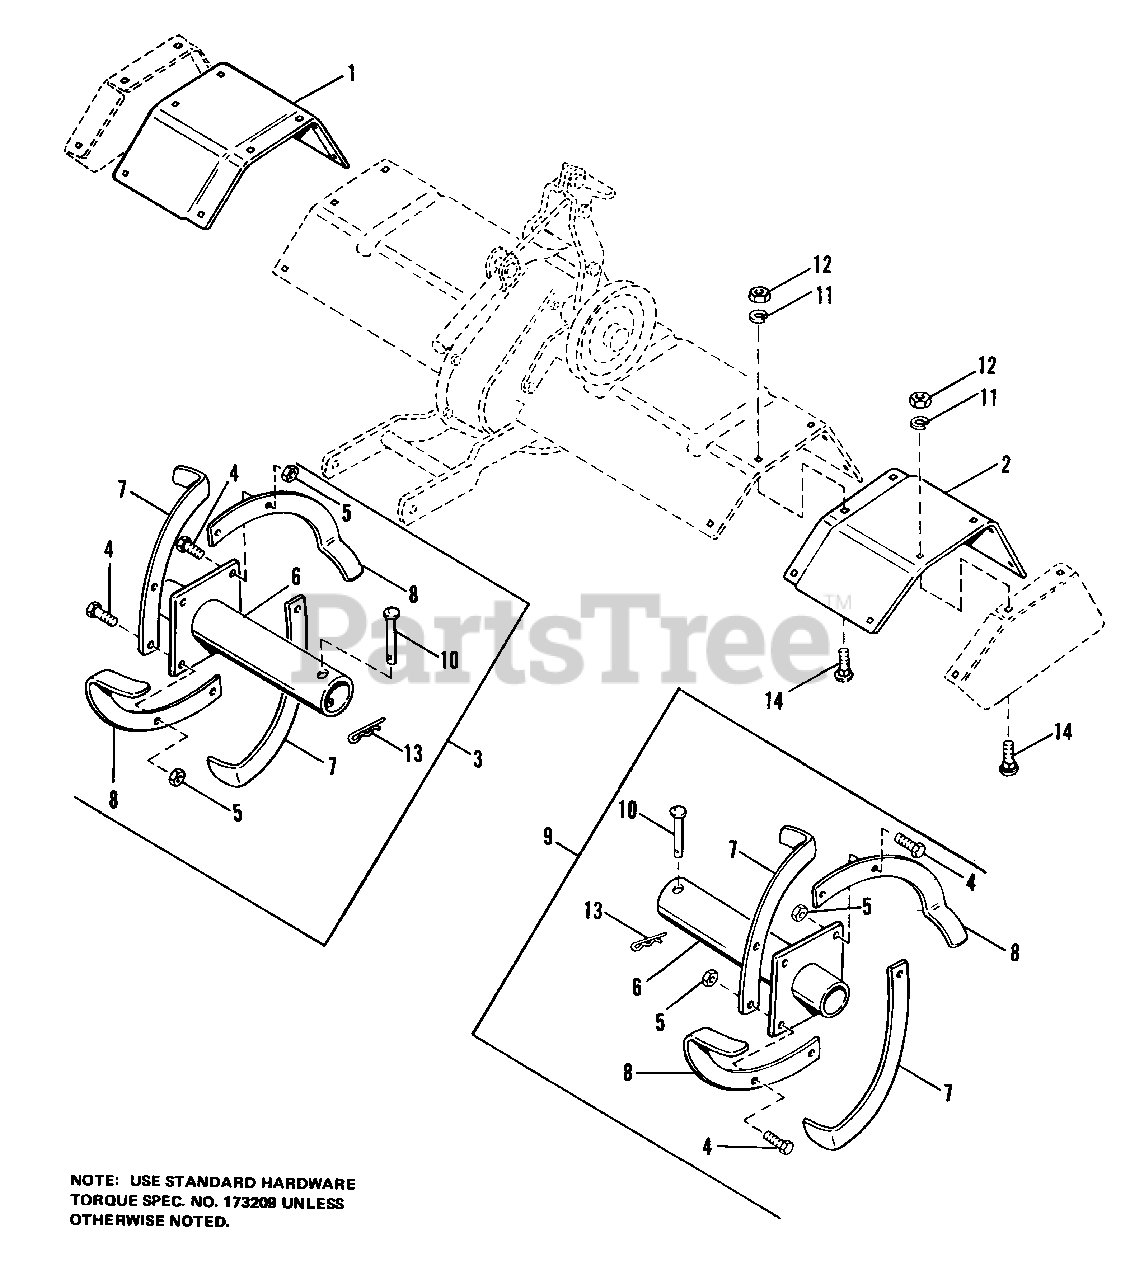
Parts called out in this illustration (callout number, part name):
1	DEFLECTOR, Ext., R.H.
2	DEFLECTOR, Ext., L.H.
3	BLADE ASSY, L.H., Tine
4	CAPSCREW, Hex Hd,, 7/16-20 x 1-1/4
5	NUT, Hex Lock, 7/16-20
6	HUB & PLATE ASSY, Outer Tine
7	TINE BLADE, L.H.
8	TINE BLADE, R.H.
9	BLADE ASSY, R.H., Outer Tine
10	PIN
11	LOCKWASHER, Spring, 5/16
12	NUT, Hex, 5/16-18
13	PIN, Quick, 1-7/8
14	BOLT, Rd., Sht. Sq. Nk., 5/16-18 x 3/4
